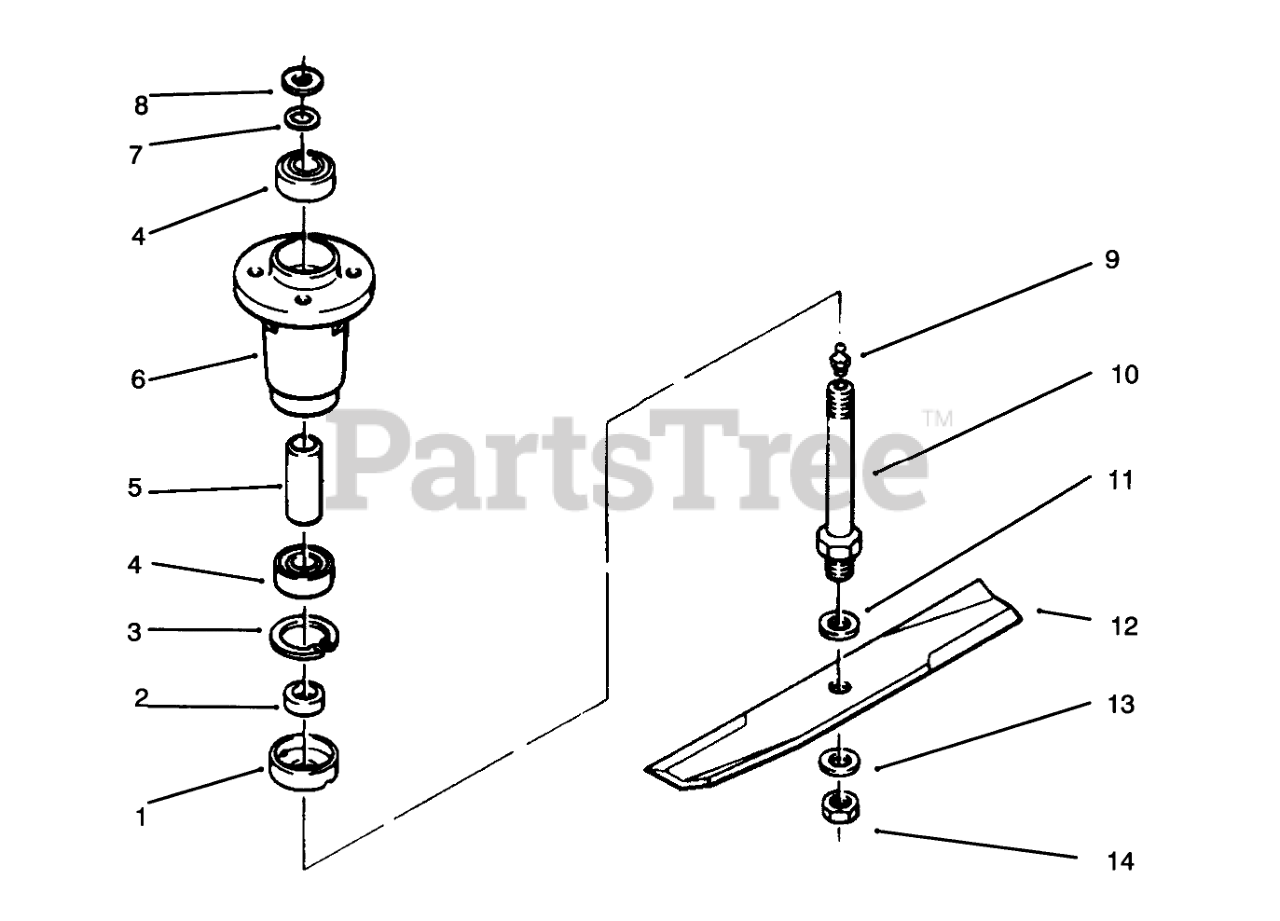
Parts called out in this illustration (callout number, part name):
1	CUP-SPINDLE
2	SPACER-BLADE
3	RING-RETAINING
4	BEARING-BALL
6	BELT-V, LOWER PTO
7	O RING
8	Washer
9	FITTING-GREASE
10	SHAFT-SPINDLE
11	Washer
12	Blade Center
13	WASHER-FLAT
14	NUT-JAM
